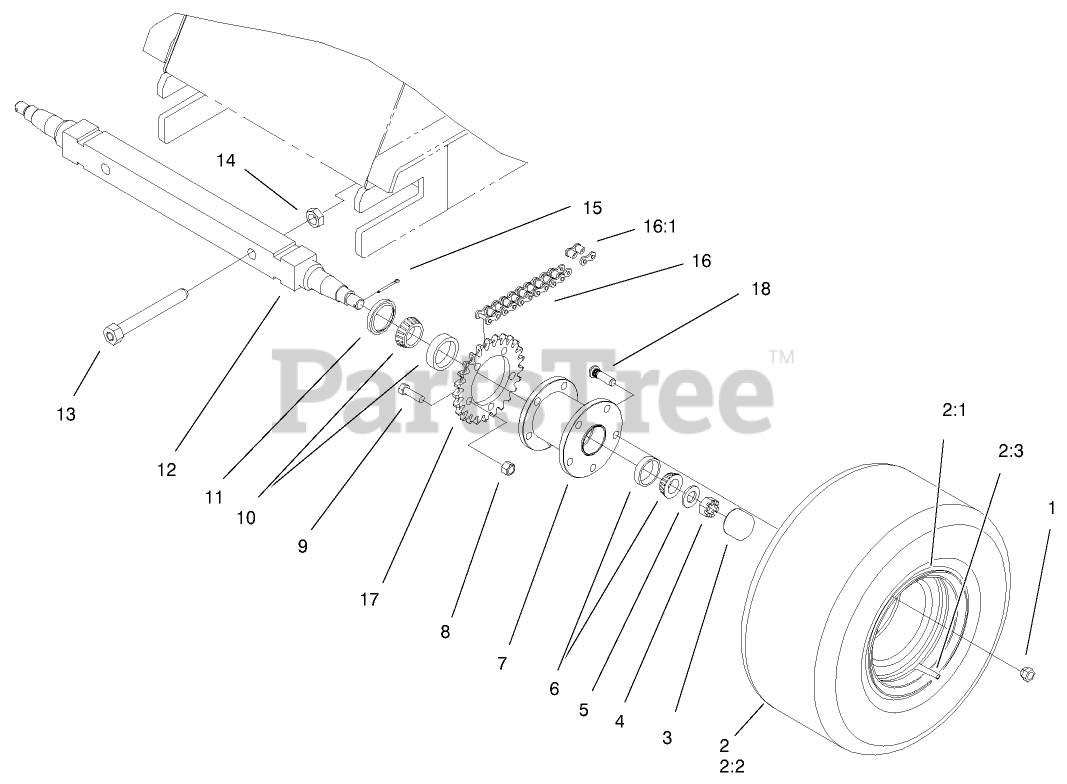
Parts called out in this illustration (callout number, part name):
1	NUT-WHEEL
2	TIRE and WHEEL ASM
2:1	WHEEL
2:2	TIRE
2:3	TUBE-TIRE
3	DUST CAP
4	LOCKNUT
5	WASHER-FLAT
6	BEARING-ROLLER TAPERED
7	HUB-FRONT
8	NUT-HEX
9	SCREW-HH
10	BEARING-CUP and CONE
11	Seal-Bearing, Wheel
12	AXLE-FRONT
13	BOLT-TENSION
14	NUT-JAM
15	PIN-COTTER
16	CHAIN-ROLLER
16:1	LINK-CONNECTING
17	SPROCKET-25T
18	STUD-DRIVE
